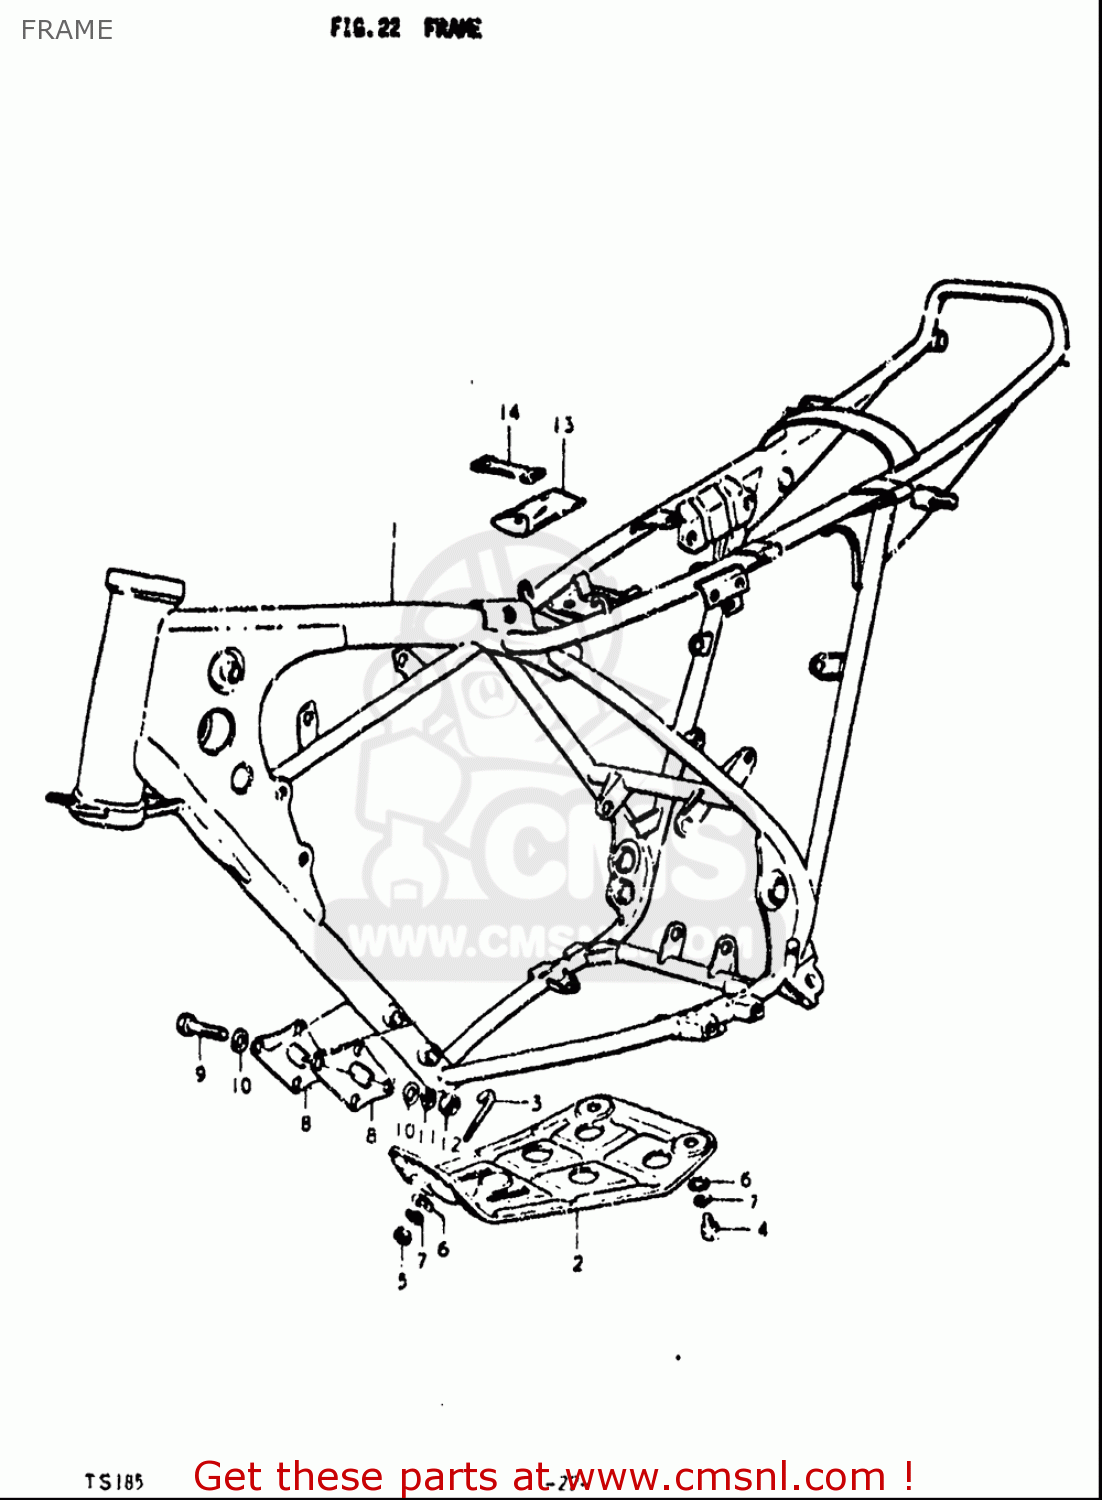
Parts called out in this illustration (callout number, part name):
4	BOLT
5	NUT
6	WASHER
7	WASHER,LOCK
9	BOLT
10	WASHER
11	WASHER,LOCK
12	NUT
13	TOOL ASSY
14	BAND
